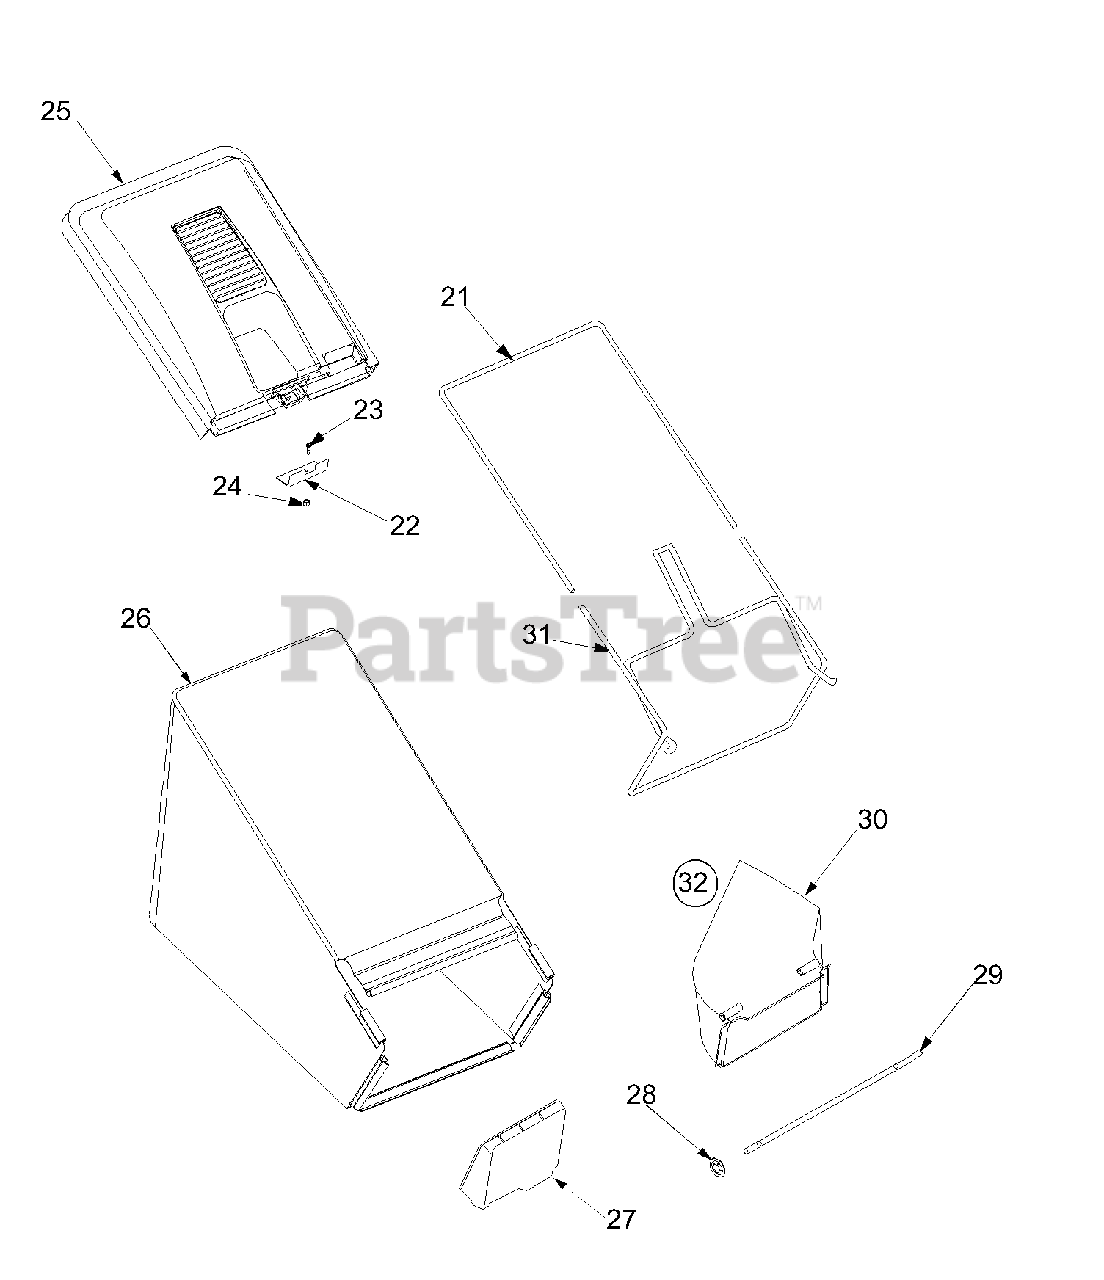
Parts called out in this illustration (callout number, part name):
23	Hex Screw 1/4 -20 x .5
24	Hex Nylon L-Nut 1/4-20
25	Hardtop Cover w/o Logo: Blk.
26	Grass Bag: Soft Top w/ Logo
27	Mulcher Plug
28	Nut: Spd. .3125 ID
30	Side Discharge Adapter
